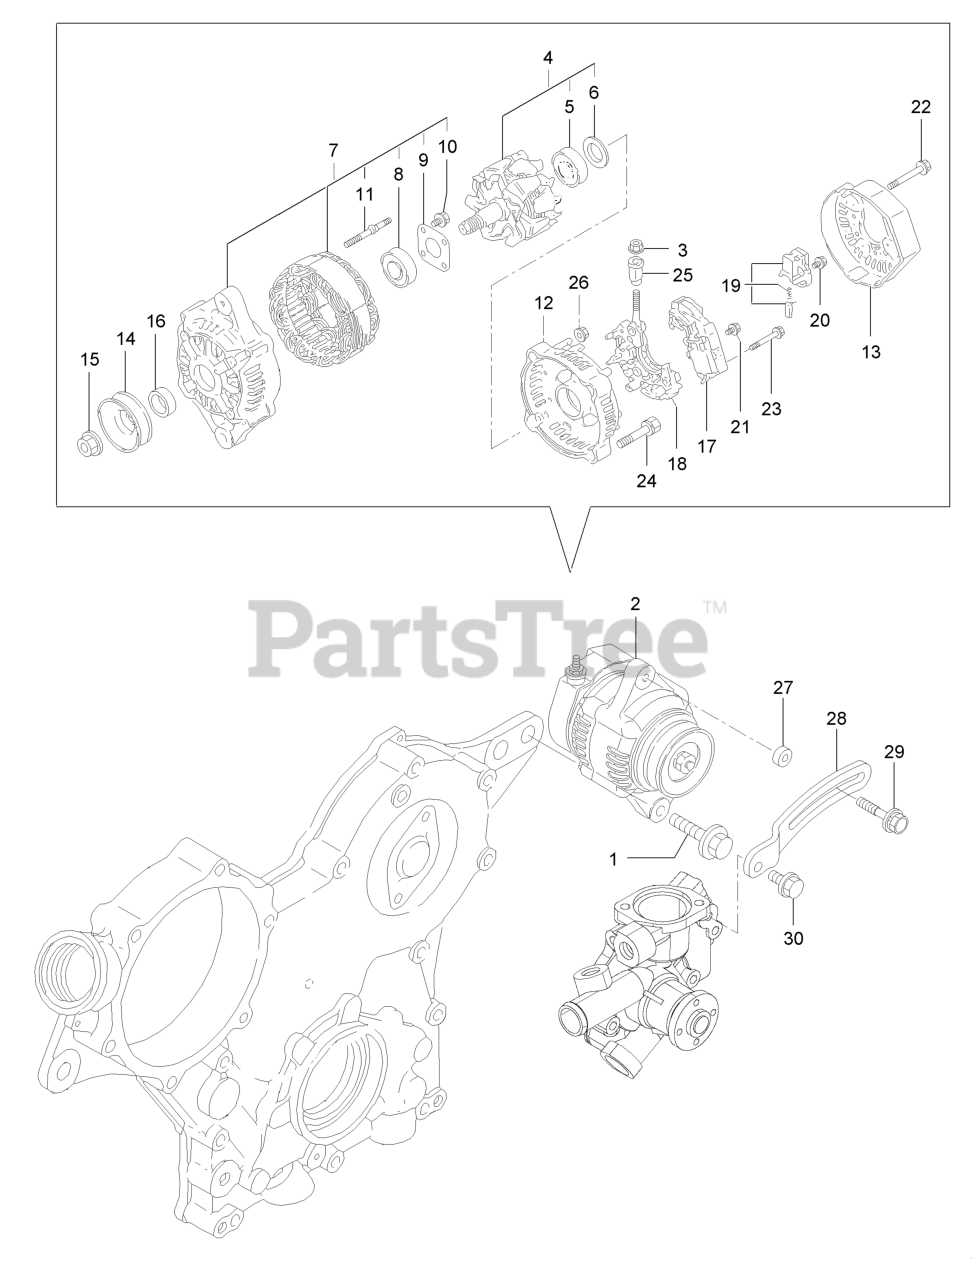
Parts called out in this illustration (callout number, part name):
2	Alternator
4	Rotor ASM
5	Bearing-Ball
7	Frame ASM
8	Bearing-Ball
9	Plate-Retainer
17	Regulator ASM
25	Bushing-Insulation
28	Adjuster-Belt
